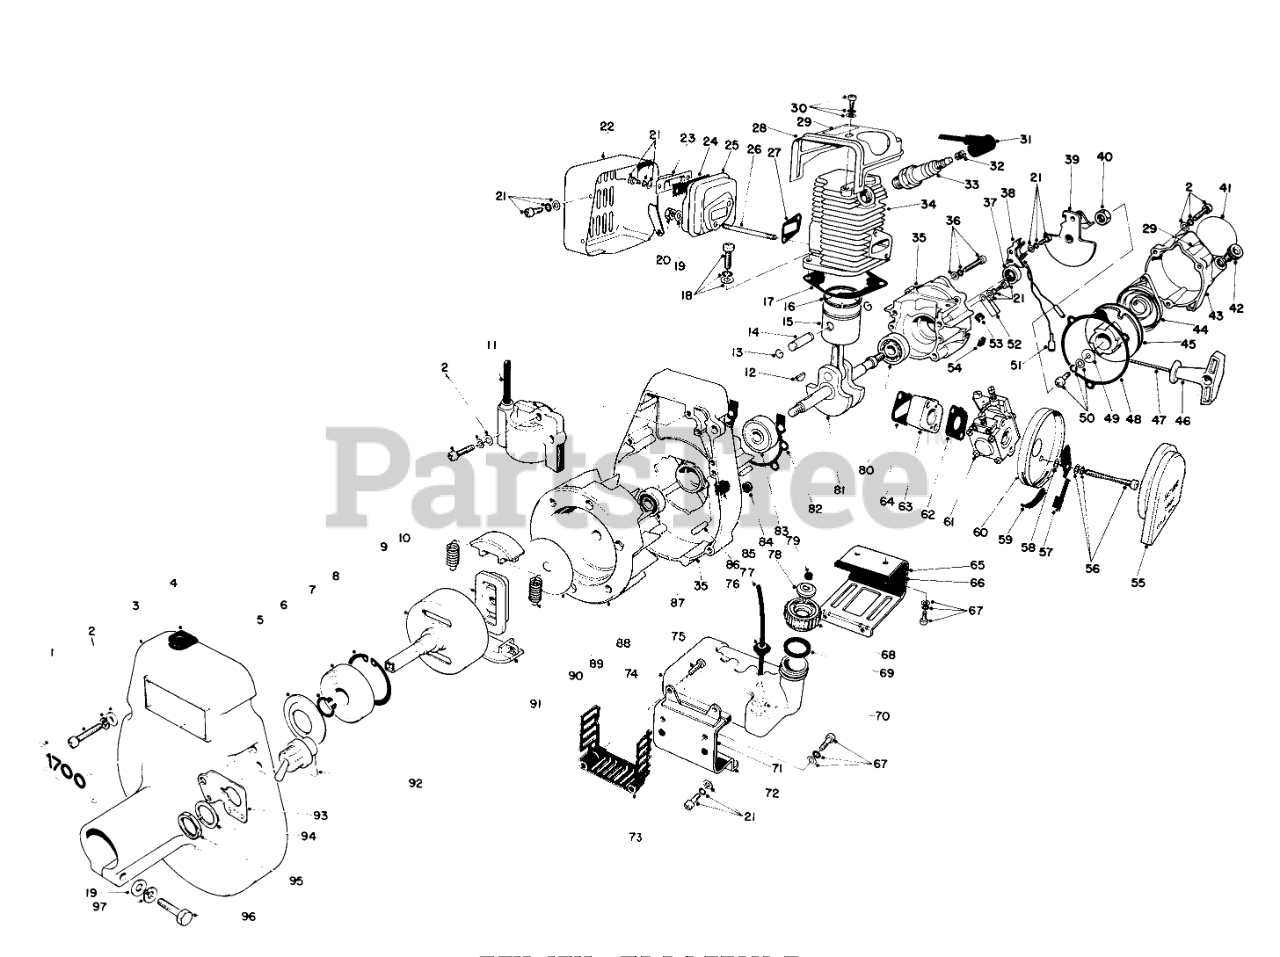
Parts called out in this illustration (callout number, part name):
1	Decal-1700
2	SCREW
3	Fan Cover
4	Grommet
5	Stopper
6	Circlip
7	Ball Bearing
8	Circlip
9	Clutch Drum
10	Clutch Boss
11	Ignition Coil
12	Woodruff Key
13	Circlip, Piston Pin
14	Piston Pin
15	Piston
16	Piston Ring
17	Gasket, Cylinder Base
18	SCREW W/WASHER
19	WASHER
21	SCREW
22	Muffler Cover
23	Lid-Muffler
24	Screen
25	Muffler Body
26	STUD BOLT
27	Gasket, Muffler
28	Cylinder Cover
29	Decal-Hot Surface
30	SCREW
31	Cap-Spark Plug
32	Coil Spring-Plug Cap
33	Spark Plug
34	Cylinder
35	Crankcase Set
36	SCREW
37	Oil Seal
38	Breaker Point Set
39	Ratchet Assembly
41	Decal
42	Rope Guide
43	Starter Case
44	REWIND SPRING
45	Recoil Drum
46	Starter Handle
47	Rope-Starter
48	Gasket-Start Case
49	Washer
50	Screw
51	Ground Lead
52	Condenser
53	Oil Pad
54	Grommet
55	Air Filter
56	SCREW
57	CHOKE SHUTTER
58	CHOKE SHUTTER SPACER
59	Grommet
60	Case-Air Cleaner
61	Carburetor Assembly
62	GASKET
63	Insulator
64	Gasket
65	Bracket-Fuel Tank
66	Cushion
67	Screw
68	Cap-Fuel Tank
69	Gasket-Fuel Tank Cap
70	FUEL STRAINER
71	Cushion
72	Bracket-Fuel Tank
73	Dust Filter
74	FUEL TANK
75	Screw
76	Grommet
77	Fuel Line
78	Check Valve
79	Filter
80	Bearing
81	Crankshaft Assembly
82	Gasket-Crankcase
83	Bearing
85	Grommet
87	Oil Seal
88	FIywheel
89	Side Plate
90	Clutch Spring
91	Clutch Shoe
92	Switch (Incl. Ref. #94, 95)
93	Bracket-Switch
94	Washer
95	Jam Nut
97	Washer
